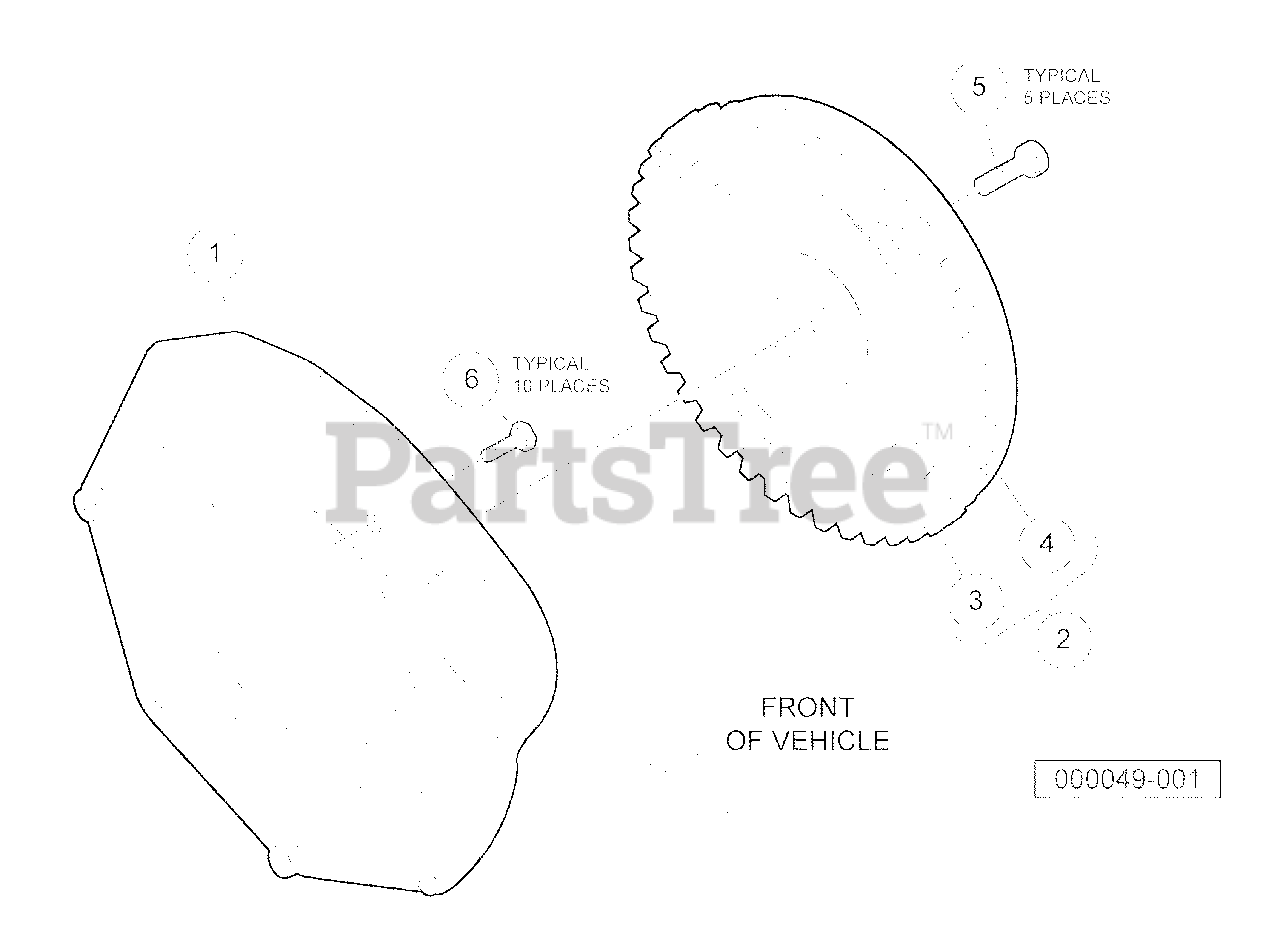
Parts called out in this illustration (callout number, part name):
1	Plate, Rear End
2	Flywheel
3	Gear, Ring, D722
4	Flywheel
5	Bolt, Flange Head, M10 X 1.5 X 25
6	Bolt, End Plate.
